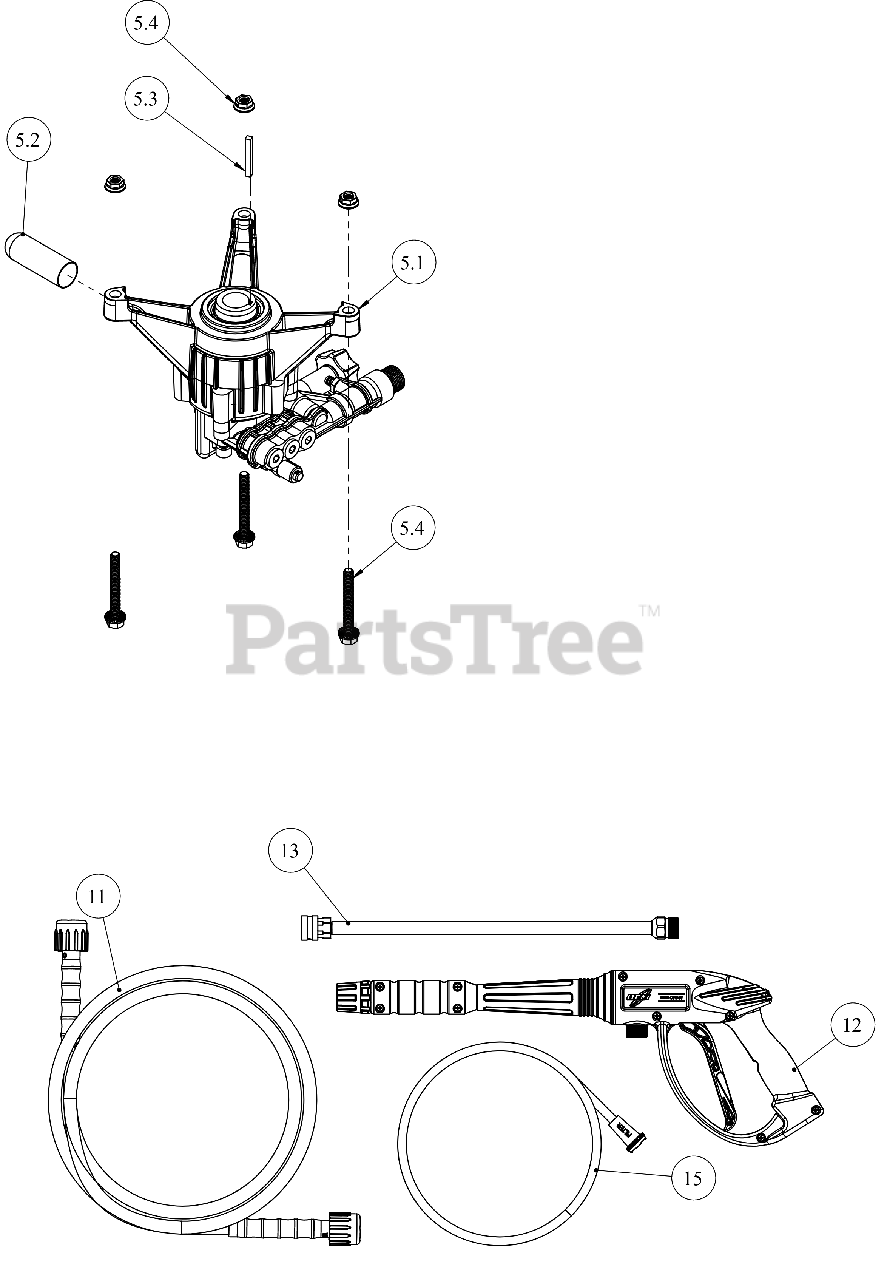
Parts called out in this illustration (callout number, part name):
5.1	PUMP (SVC 510020)
5.2	UNLOADER CAP
5.3	SHAFT KEY (3/16x3/16x1.5)
5.4	HARDWARE KIT-PUMP MTG
11	SPRAY GUN HOSE 30'
12	SPRAY GUN FRONT ENTRY
13	WAND-SPRAY GUN 16"
15	HOSE-SOAP W/FILTER
